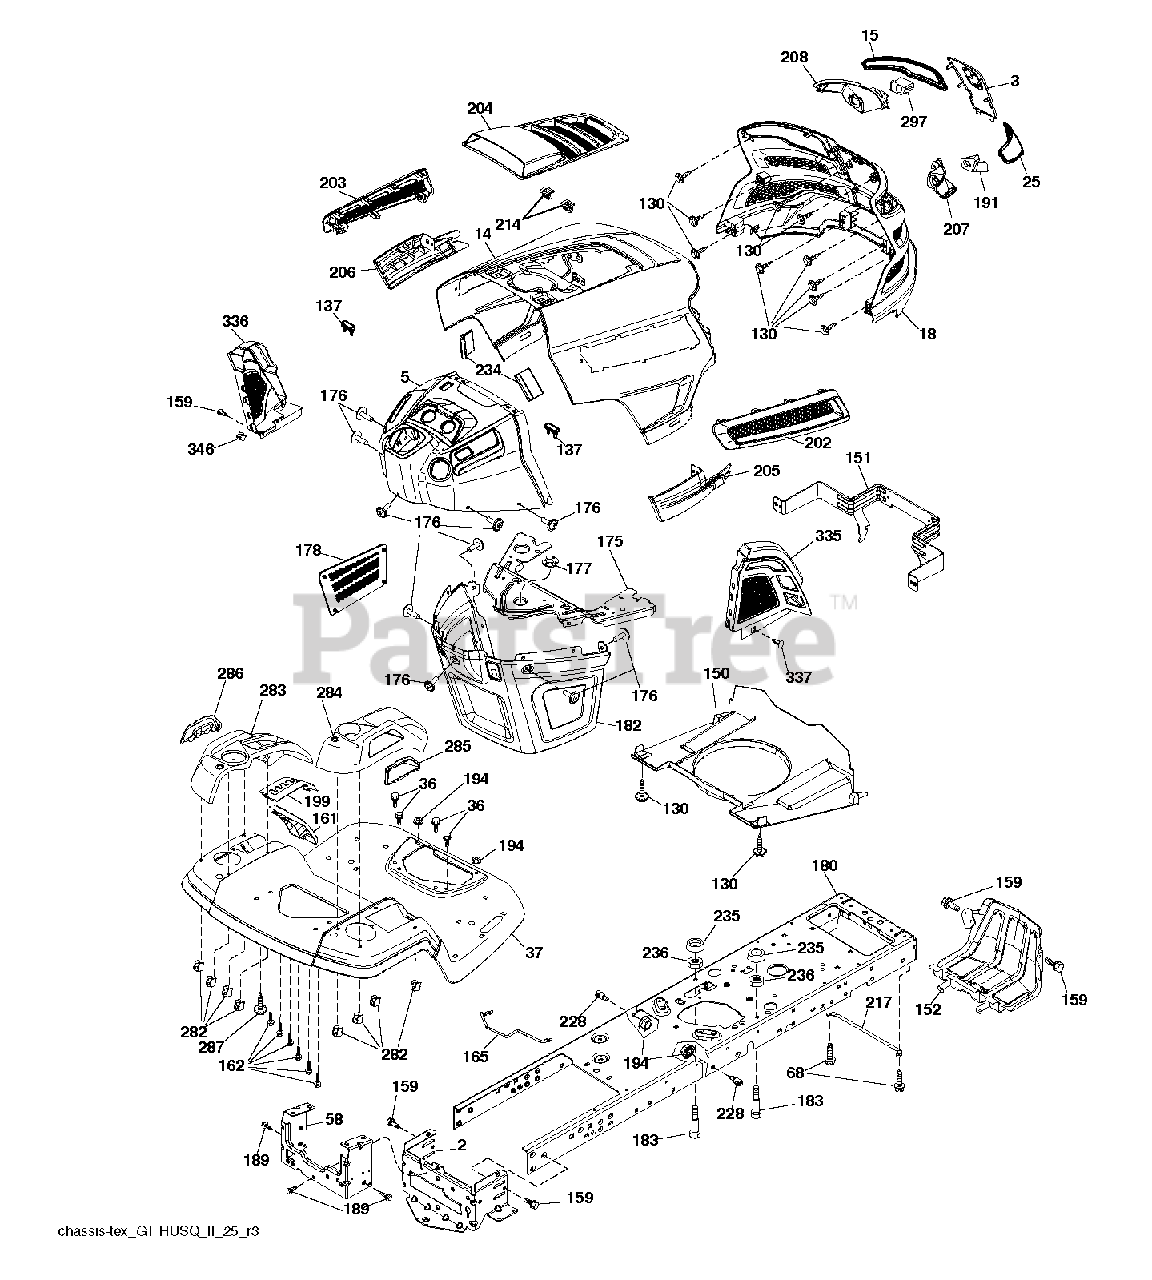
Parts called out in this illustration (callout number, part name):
2	DRAWBAR.LOWER.2PC.18/22
3	APPLIQUE.SUBASM.GT.HUSQ.II
5	DASH.UPP.GT2.DUAL.RD.PTO.MCHOK
14	HOOD.ASM.HUSQVARNA.GT.TEX.ORAN
15	LENS.HEADLIGHT.LH.GTII.2011
18	GRILLE.SUBASM.GT.HUSQ.II
25	LENS.HEADLIGHT.RH.GTII.2011
36	SCREW 5/16"
37	FENDER.TLT.FS.W/CPH/FW/RSF.668
58	DRAWBAR UPPER 2PC SMALL FENDER
68	SCREW LT
130	SCREW.#10 X 0.750.BOS
137	BUMPER DASH
150	AIR.DUCT.GTV.BLACK
151	BRACKET.PIVOT.HOOD.GT.HUSQ.II
152	SHIELD.BROWNING.PNT.GT.V2
159	SCREW, 3/8-16X3/4
161	WINDOW.FUEL.LT.HUSQ.TEX.498
162	SCREW.HI-LO.CONSOLE
165	SUPPORT.TANK.REAR.B/TE
175	PLATE.CROSSMEMBER.HUSQ
176	SCREW.#10-24X5/8.RN.QU
177	BUSHING, STEERING
178	CARGO.ASM.NET.TXGT.W/C
180	CHASSIS.STAMPING.LT/GT
182	DASH.LOWER.COMMON.12V.ADAPTOR
183	BOLT.5/16-18X1-1/4 FULL THD
189	SCREW
191	INSERT.REFLECTIVE.RH.HUSQ.GTII
194	NUT LOCK HEX FLANGE 5/16-18
199	PLATE.DECK.LIFT.HUSQ.LT
202	VENT.SIDE.RH.GT.HUSQ.II.
203	VENT.SIDE.LH.GT.HUSQ.II.498
204	VENT.TOP.HUSQ.GT2
205	SIDE.TRIM.RH.GT.HUSQ.II
206	SIDE.TRIM.LH.GT.HUSQ.II.GRAY
207	BEZEL LIGHT.RH.GT.II.MYLAR
208	BEZEL LIGHT.LH.GT.II.MYLAR
214	CLIP.RETAINER.TINNER.
217	ROD.PIVOT.HOOD
228	STUD.FASTNER.W/ANTI-ROTATE
234	BUMPER.HOOD.TEX.HUSQVARNA
235	SPACER FENDER
236	NUT.CENTERLOCK.5/16-
282	CLIP.RETAINER.CONSOLE.LT.HUSQ
283	CONSOLE.DECK.LIFT.R.SDFL.HUSQ
284	CONCOLE.CNTRL.PDL.HUSQ.LT.498
285	CONSOLE INSERT RH
286	CONSOLE.INSRT.LH.HUSQ.LT.BLACK
287	SCREW 1/4X20
297	INSERT.REFLECTIVE.LH.HUSQ.GTII
335	COVER.RH.CLOSE.OUT.BLACK
336	COVER-LH.LOWER.DASH.GT2.BLACK
337	CLIP.XMAS.TREE.ITW.2622-00
346	CLIP,INSULATOR
